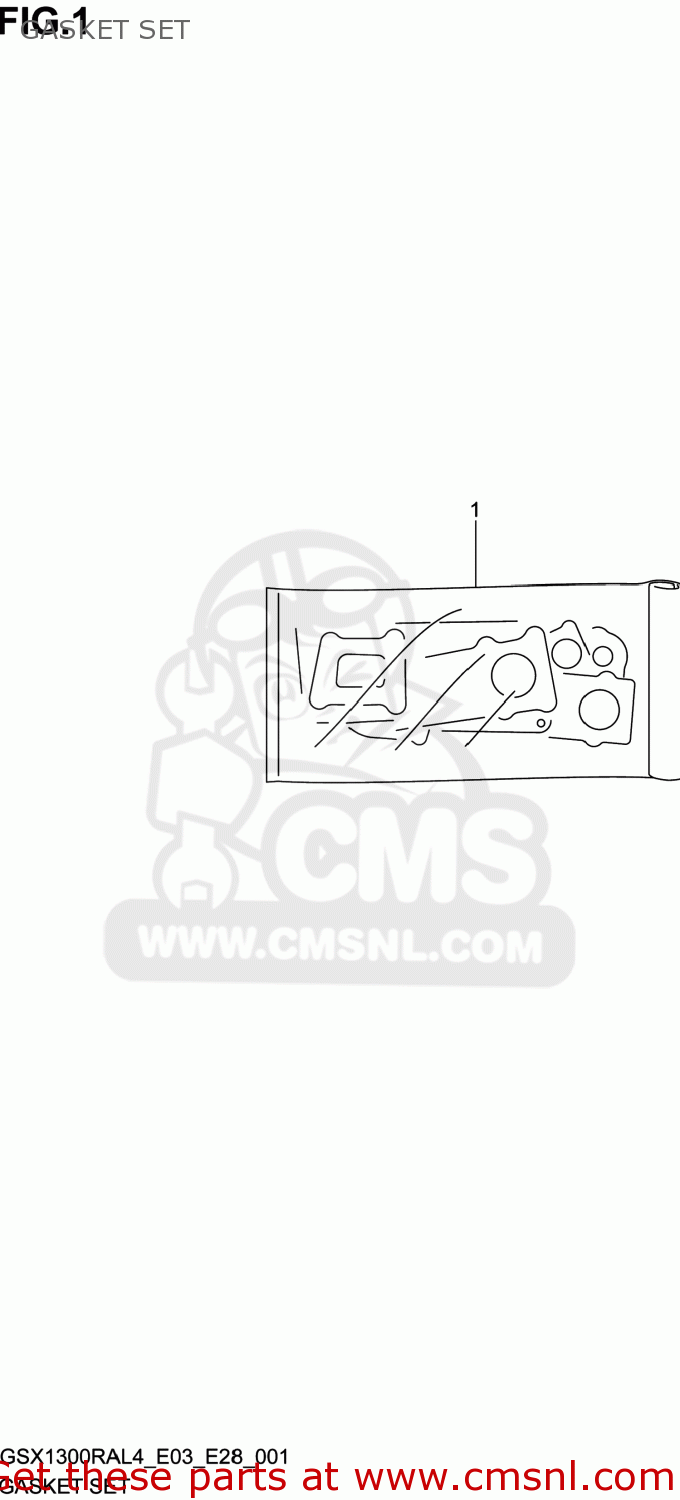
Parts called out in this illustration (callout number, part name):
1	GASKET SET (NAS)
2	GASKET,CYLINDER HEAD (NAS)
3	GASKET,CYL HEAD COVER NO.1 (NAS)
4	GASKET,CYL HEAD COVER NO.2 (NAS)
5	GASKET,CYLINDER (NAS)
6	GASKET,CL COVER (NAS)
7	GASKET,MAGNETO COVER (NAS)
8	GASKET,GEAR SHIFT COVER (NAS)
9	GASKET,OIL PAN(ASB) (NAS)
10	GASKET,STARTER CLUTCH COVER (NAS)
11	GASKET,START IDLE GEAR CAP (NAS)
12	GASKET,TENSIONER ADJUSTER (NAS)
13	GASKET,EXHAUST PIPE (NAS)
14	WASHER,CYL HEAD COVER
